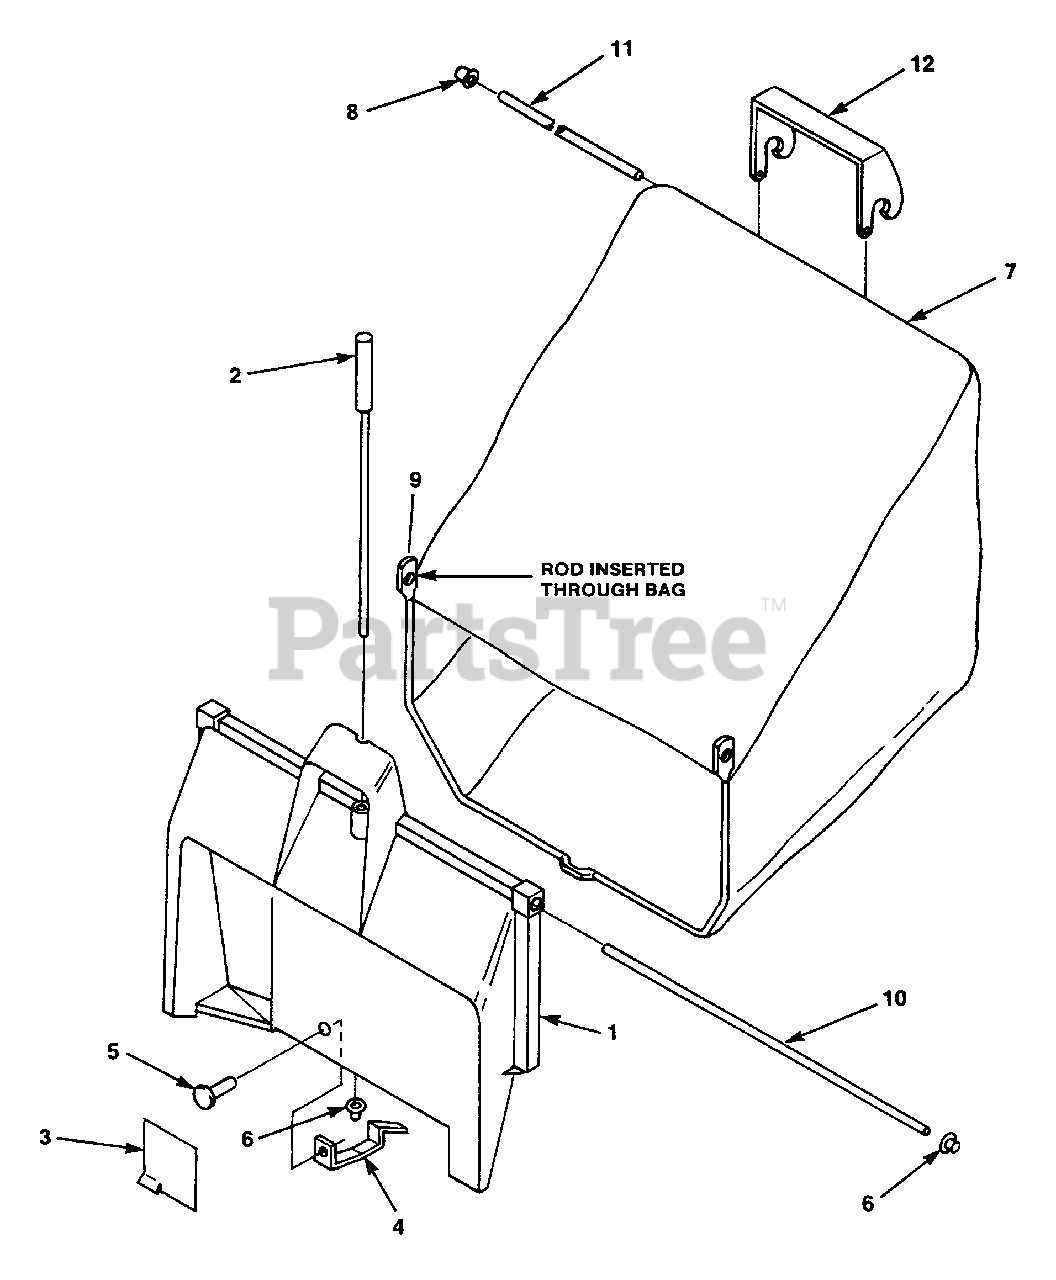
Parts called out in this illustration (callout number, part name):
1	ADAPTOR- Bag
2	ROD- Latch release
3	DEFLECTOR
5	RIVET- Pop 5/32 x 3/8
7	GRASS CATCHER-
9	ROD- Bag Support
10	ROD- Bag hinge
11	ROD- Upper bag
12	HANDLE- Upper bag
